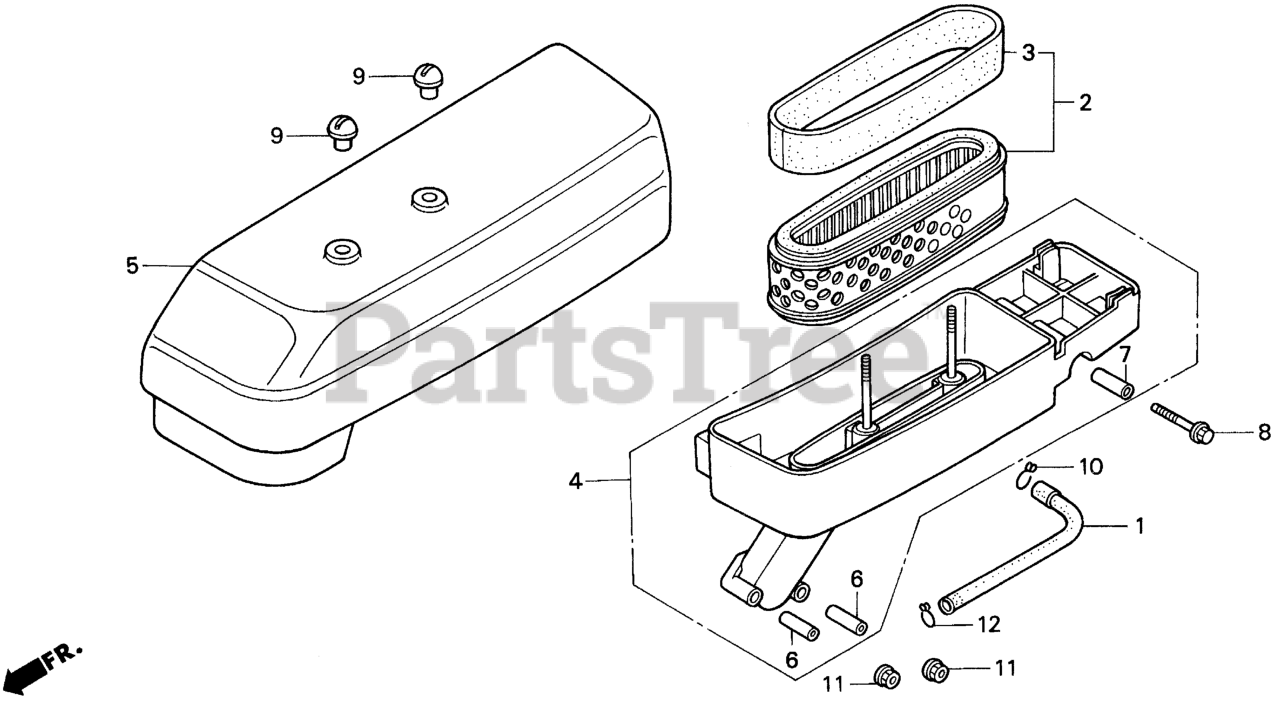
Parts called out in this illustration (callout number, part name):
1	TUBE, BREATHER
2	ELEMENT, AIR CLEANER
3	FILTER (OUTER)
4	HOUSING, AIR CLEANER
5	COVER, AIR CLEANER *R8* (BRIGHT RED)
6	COLLAR, AIR CLEANER Use from Engine SN 1786085.
7	COLLAR B, AIR CLEANER
8	BOLT, FLANGE (6X35)
9	NUT, AIR CLEANER COVER (6MM)
10	CLIP, TUBE
11	NUT, FLANGE (6MM)
12	CLIP, TUBE (B12) Use from Engine SN 2086984.
